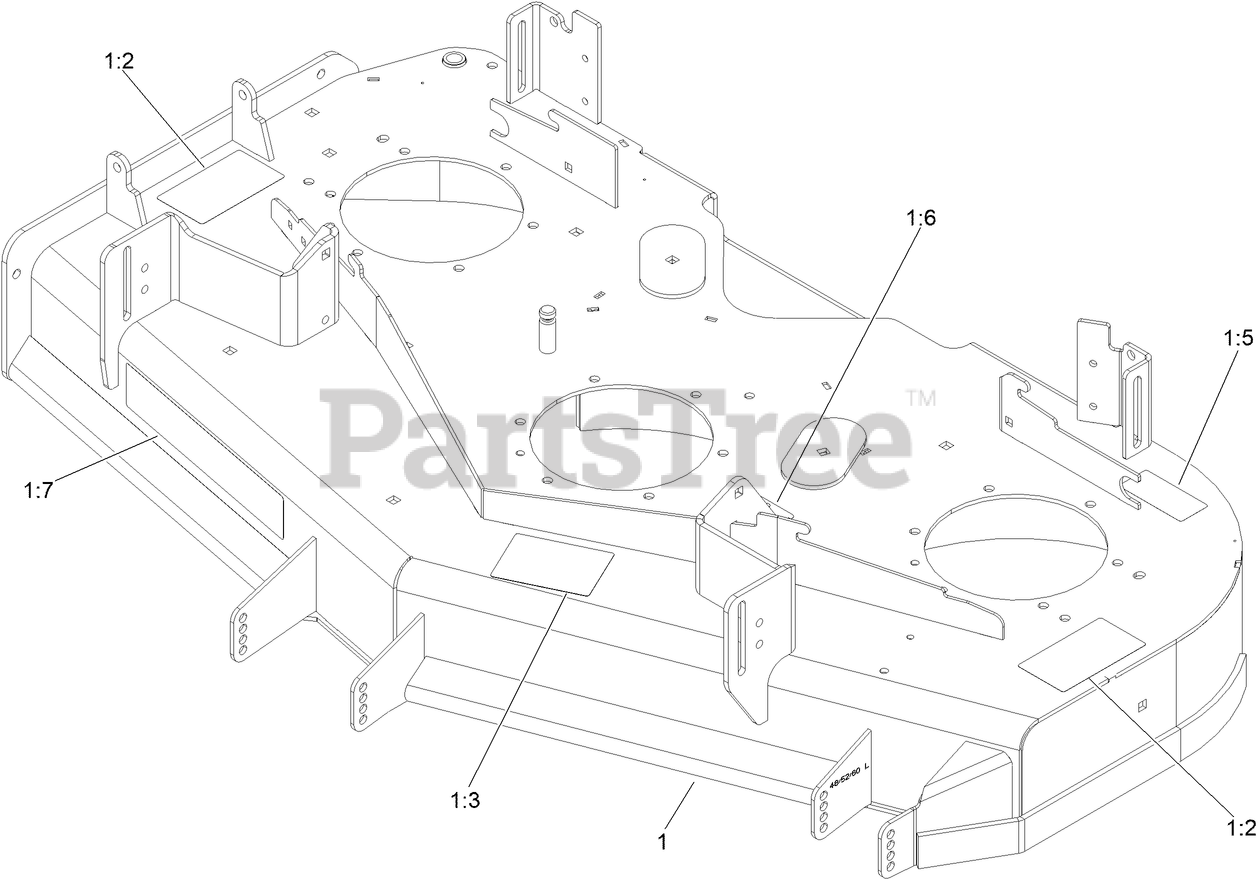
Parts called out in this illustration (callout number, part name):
1:2	DECAL-DANGER
1:3	DECAL-SCALP, ANTI
1:5	DECAL-BOLT TORQUE
1:6	DECAL-ROUTING, BELT
